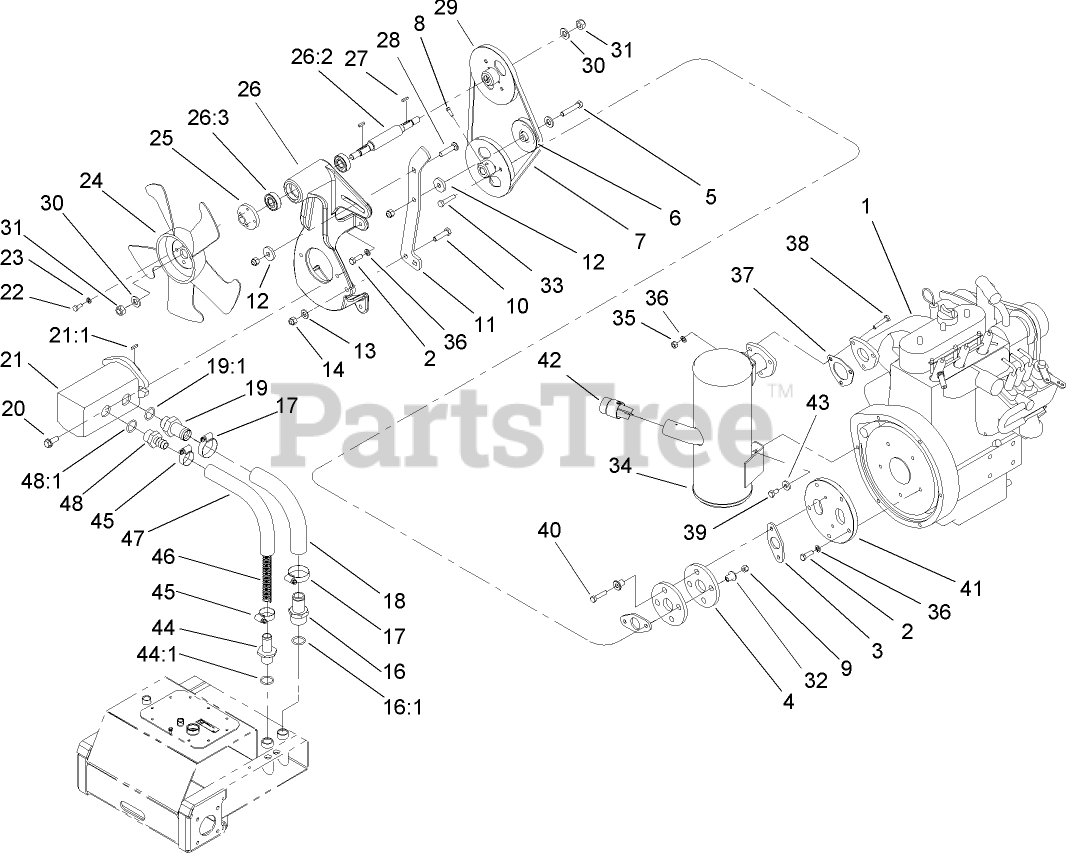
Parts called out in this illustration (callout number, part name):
1	ENGINE-KUBOTA
3	SPACER-COUPLER
4	COUPLING-RUBBER
5	SCREW-HH
6	PULLEY-IDLER
7	V-BELT
8	SCREW-SET
9	NUT-LOCK
10	SCREW-HH
11	ARM-TENSIONER
12	SPACER
13	WASHER-FLAT
14	NUT-LOCK, NI
16	FITTING-STR
16:1	O-RING
18	HOSE-SUCTION, FORMED
19	FITTING
19:1	O-RING
20	SCREW-HHF
21	PUMP-GEAR, TANDEM
21:1	KEY-SQUARE
22	SCREW-HH
23	WASHER-LOCK
25	ADAPTER-FAN
26	PUMP MOUNT ASM
26:2	SHAFT-FAN
26:3	BEARING-BALL
27	KEY-SQUARE
28	SCREW-CARR
29	PULLEY-KEYED
30	WASHER-FLAT
31	NUT-LOCK
32	SPACER
33	SCREW-HH
34	MUFFLER
35	NUT-HEX
36	WASHER-LOCK
37	GASKET-MUFFLER
38	SCREW-HH
39	BOLT
41	ADAPTER-FLYWHEEL
42	SCREEN-ARRESTER, SPARK
43	WASHER-FLAT
44	FITTING-HOSE, BARBED
44:1	O-RING
45	CLAMP-HOSE
46	Spring-Compression
47	HOSE-SUCTION, HYD
48	FITTING-STRAIGHT
48:1	O-RING
